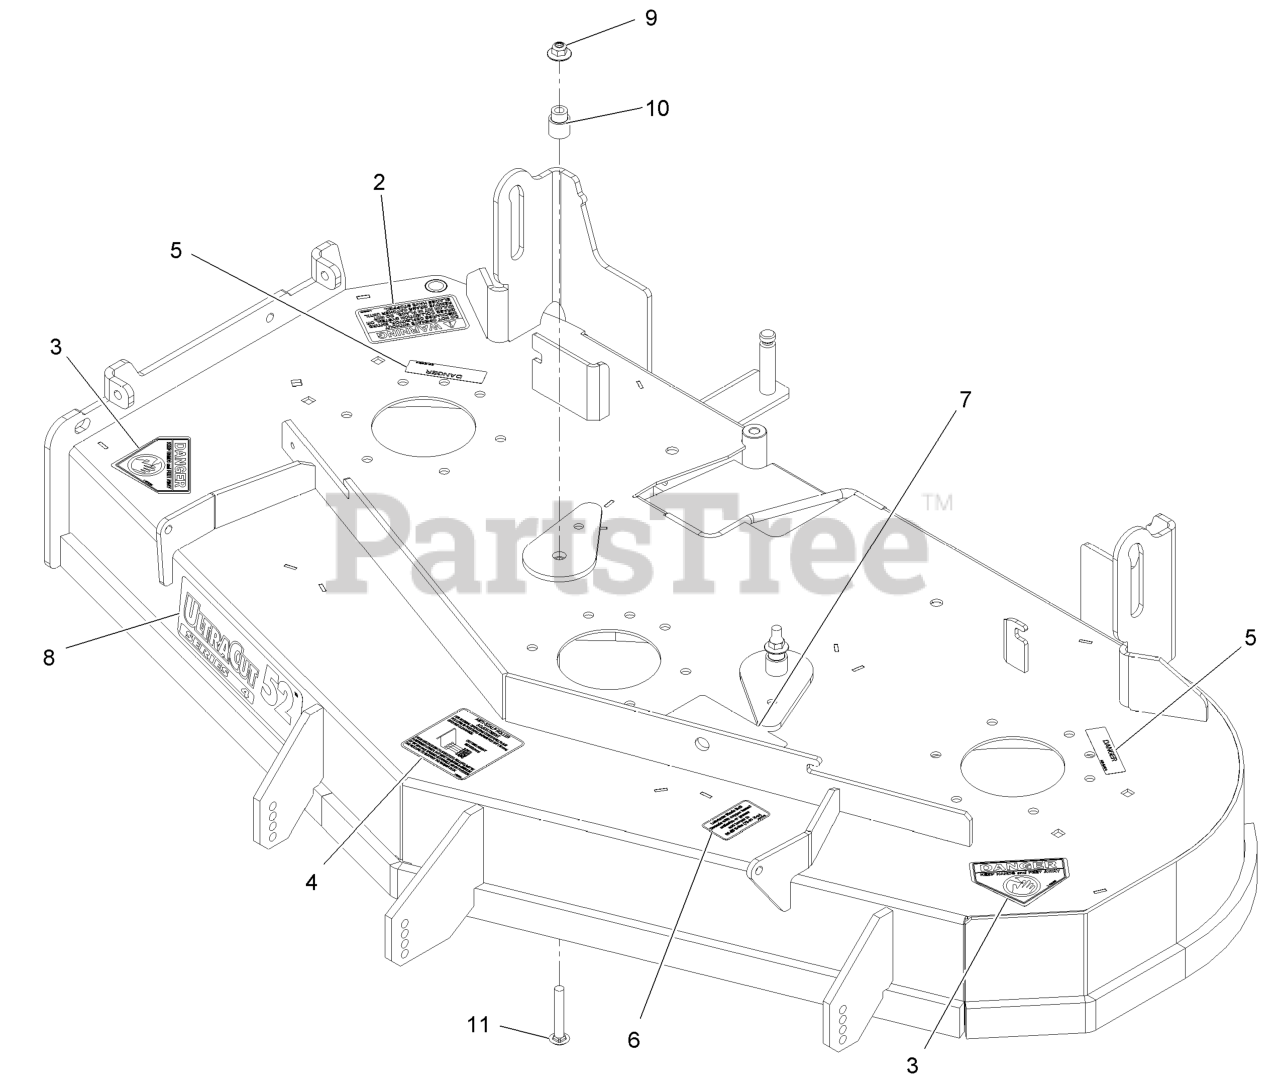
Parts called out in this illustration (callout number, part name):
2	DECAL-WARNING, DISCHARGE
3	DECAL-DANGER
4	DECAL,ANTISCALP
5	DECAL-COVER, MISSING
6	DECAL,BOLT TORQUE
7	DECAL-BELT ROUTING
8	DECAL,ULTRACUT 52 SERIES
9	Nut-Nyloc 3/8-16 Flg
10	BUSHING-IDLER
11	SCREW-CARR
